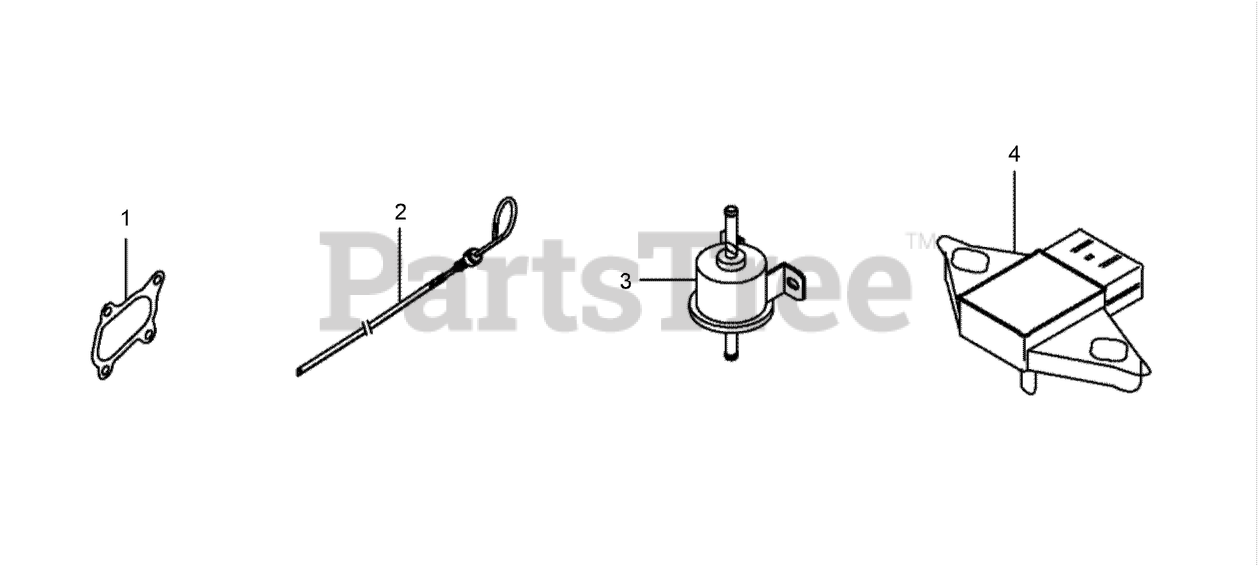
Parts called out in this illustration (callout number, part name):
1	GASKET-OUT, T C
2	DIPSTICK, LUB.OIL
3	PUMP-FUEL, ELECTRIC
4	SENSOR-ATM
